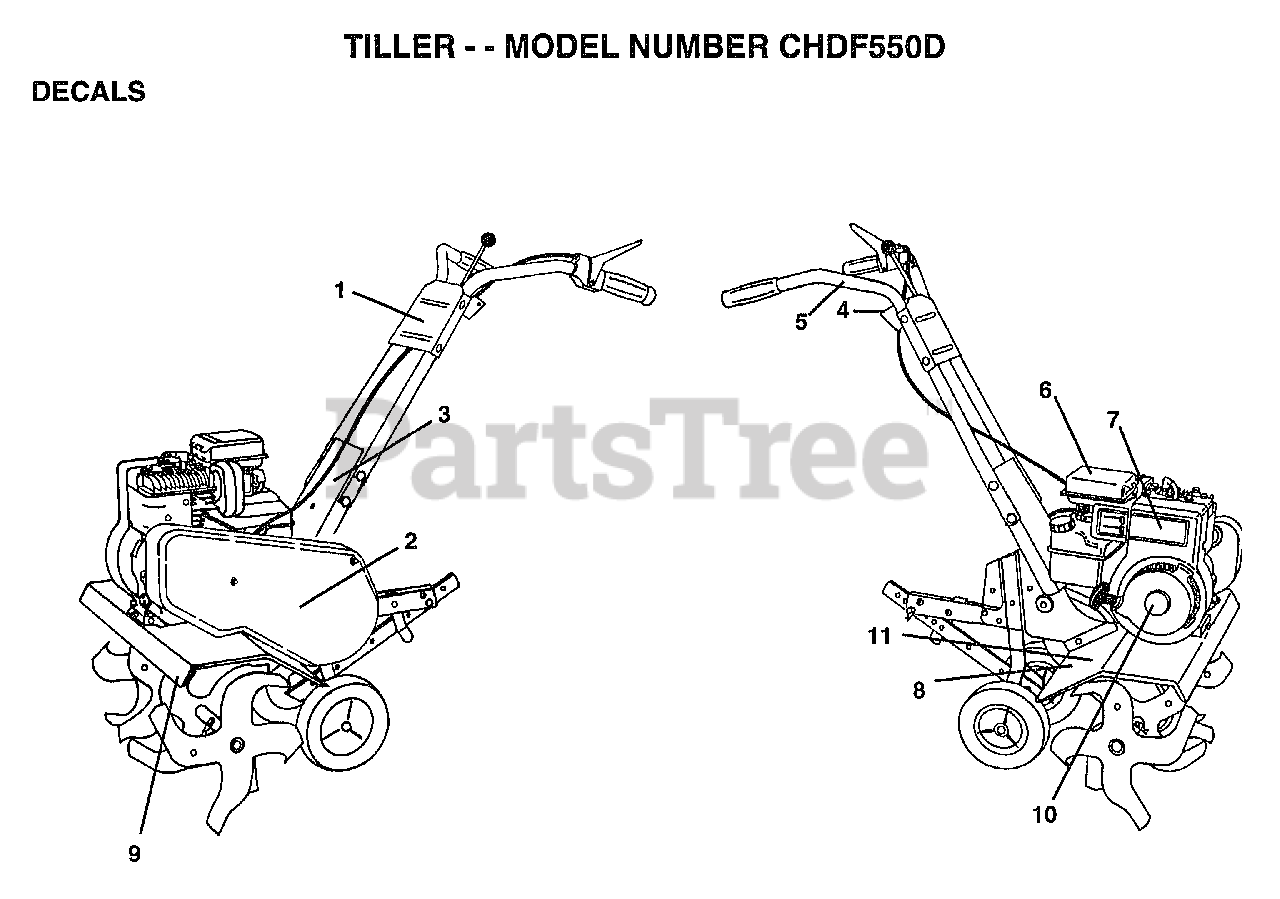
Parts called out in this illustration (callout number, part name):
1	"DECAL PANEL,CTRL"
2	"DECAL GUARD,BELT"
3	"DECAL PANEL,FORWD"
4	DECAL REVERSE
5	DECAL TI
6	DECAL TI
7	DECAL, BRIGGS & STRATTON
9	"DECAL SHIELD,TINE"
11	DECAL.CAUTION
